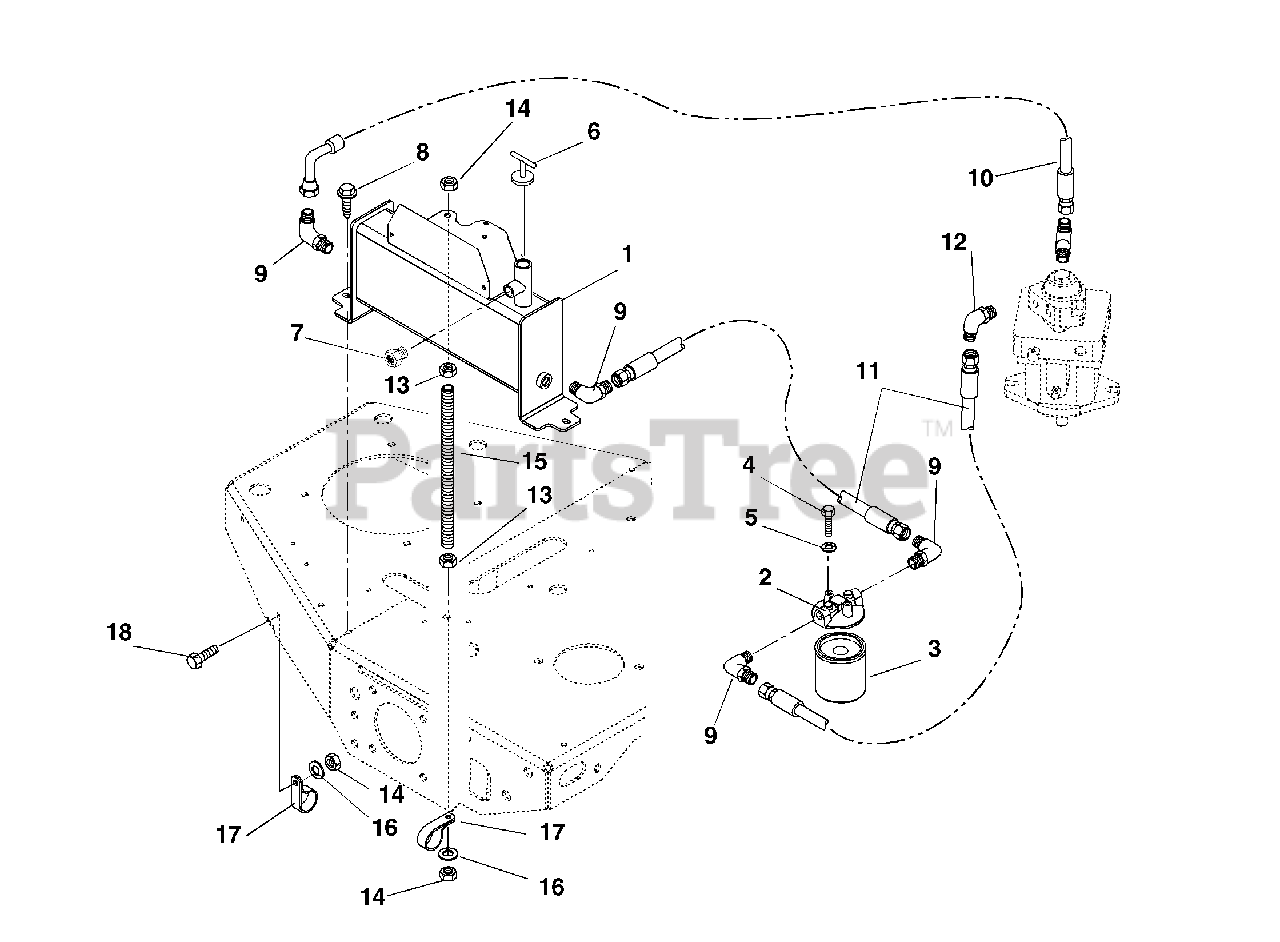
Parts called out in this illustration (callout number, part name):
1	Weldment, Hydraulic Tank
2	Head, Filter
3	Filter, Oil
4	Bolt-Hex .25-20 x .50 Grade 5
5	Washer-Locking .25 x .062 Regular
6	Dipstick, Hydraulic Tank
7	Plug, Breather .38"
8	Screw-Tapping .38-16 x .75 Hex Washer Head
9	Fitting, Hydraulic
10	Hose, Hydraulic
11	Hose, Hydraulic
12	Fitting, Hydraulic Elbow
13	Nut-Hex .38-16
14	Nut-Locking-Nylon .38-16
15	Rod, Extension
16	Washer-Flat-Steel .406 x .812 x .065
17	Clamp, Nylon
18	Bolt-Hex .38-16 x 1.00 Grade 5
